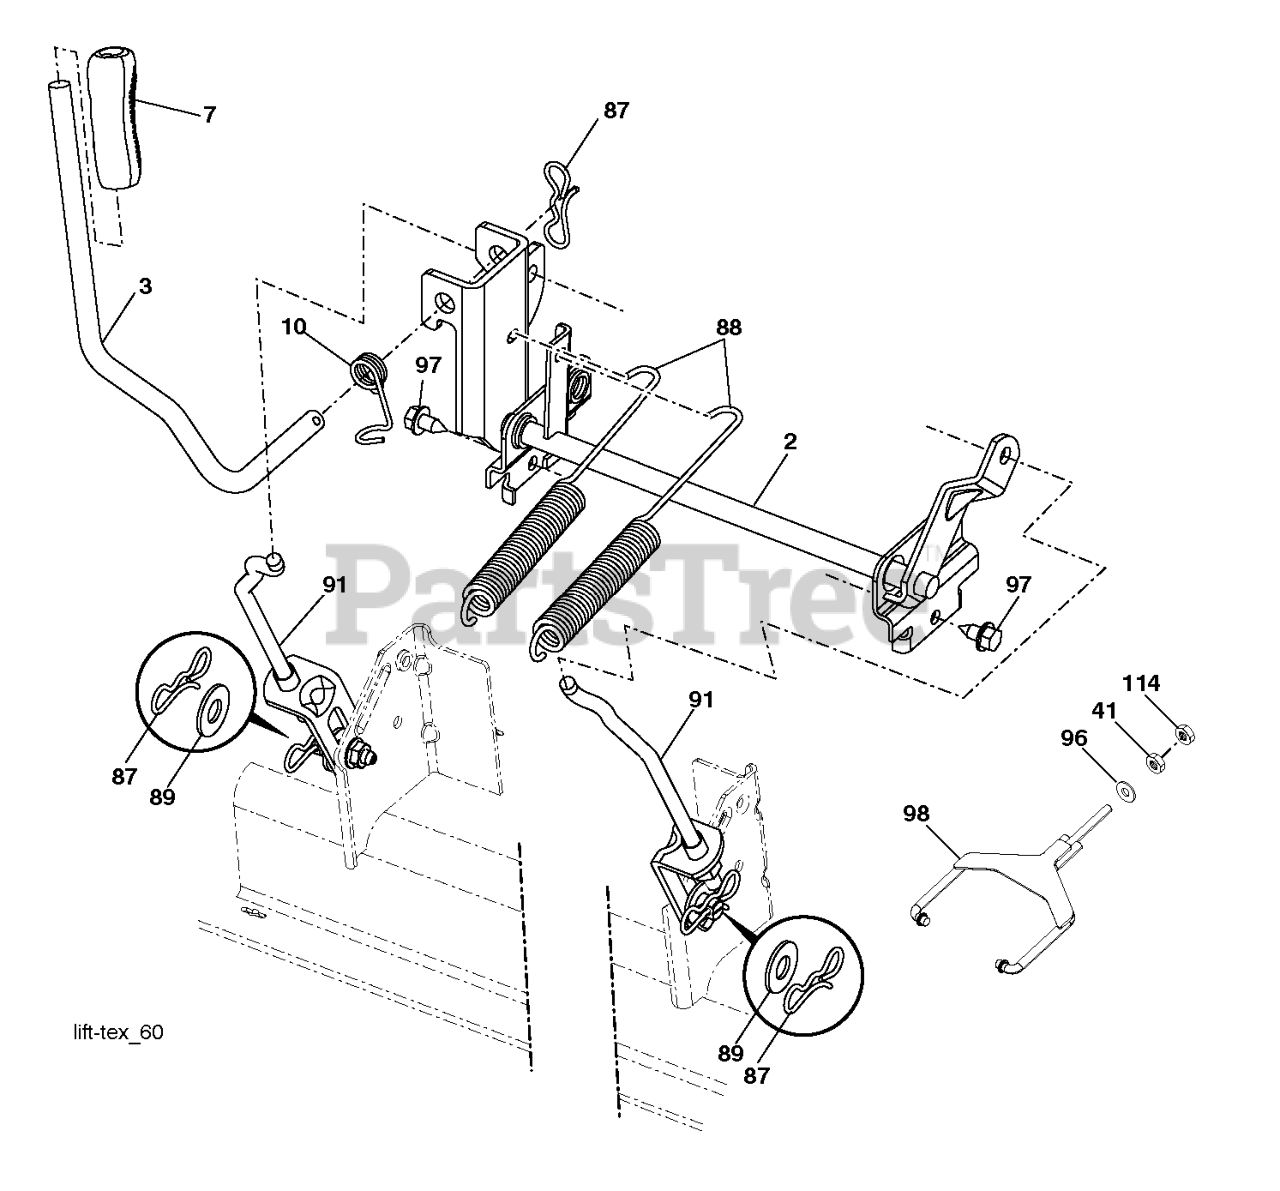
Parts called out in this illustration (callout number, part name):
2	SHAFT.ASM.CROSS.LIFT
3	Levers
7	GRIP.HANDLE.LIFT.PVC.BLACK
10	SPRING.TORSION.LIFT.HANDLE
41	NUT.LIFT LNK.7/16-2
87	PIN.COTTER.7/16.BOW TI.
89	WASHER.CLEAR.ZINC
91	Links
97	SCREW, 3/8-16X3/4
98	DECK ATTACHMENT FRONT LINK WEL
114	NUT **
